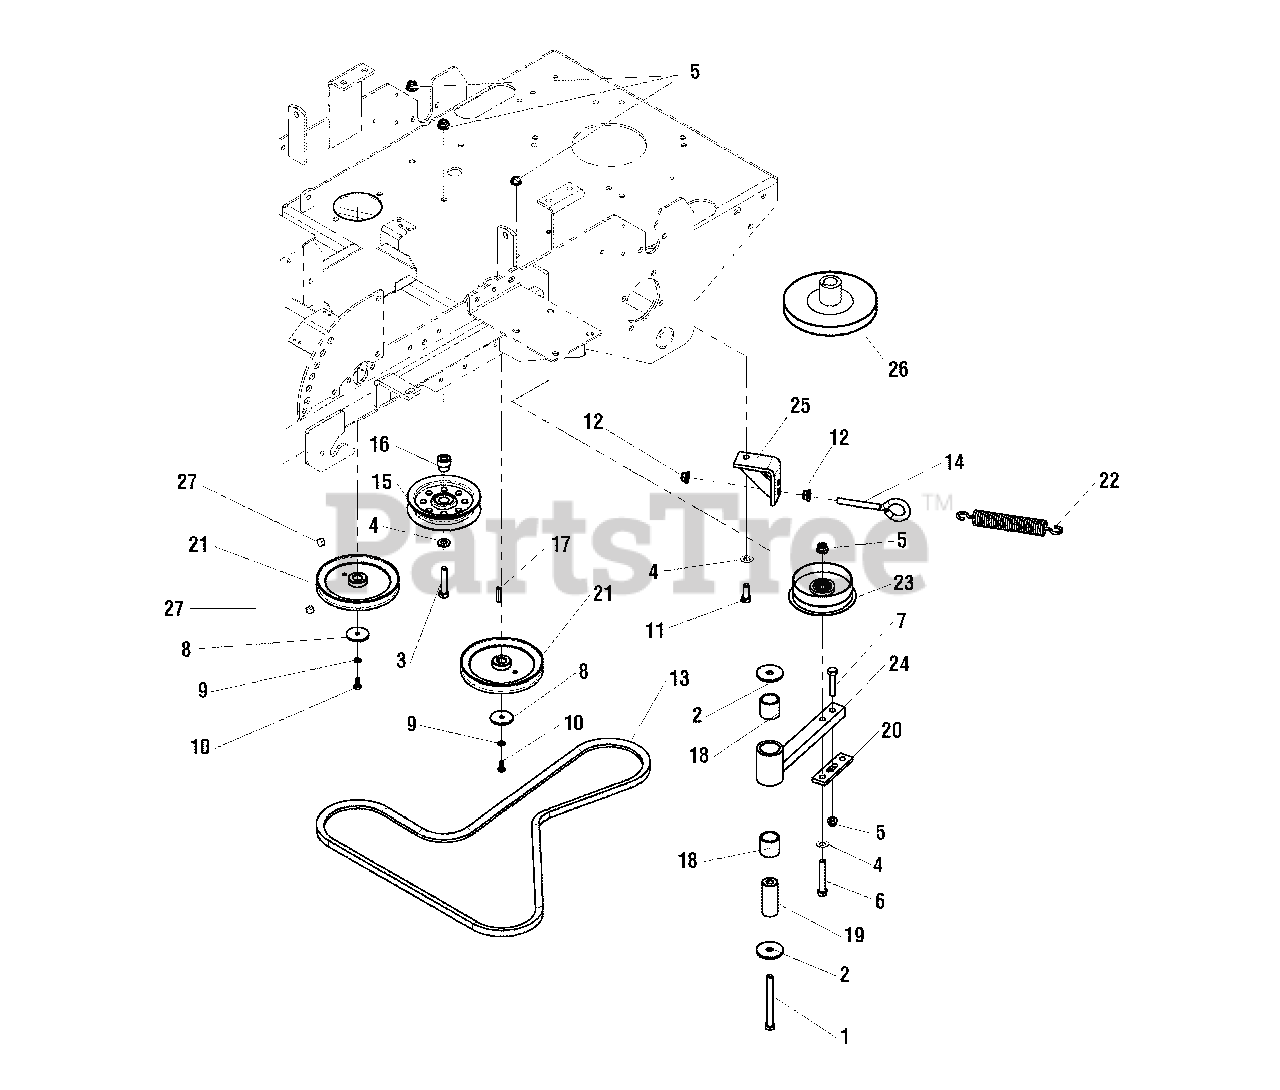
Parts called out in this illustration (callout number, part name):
1	BOLT, 3/8-16 X 4" GD5 CZ
2	WASHER, .41 X 1.75 X .14
3	BOLT, 3/8-16 X 2, GD5, CZ
4	WASHER, 3/8 SAE
5	NUT, 3/8-16 HEX NYLOCK FLANGE
6	BOLT, 3/8-16 X 2-1/2" GD5 CZ
7	BOLT, 3/8-16 X 1-3/4" GD5 CZ
8	WASHER, .265 X 1.50 X .109, YZ
9	WASHER, 1/4" LOCK
10	BOLT, M6-1.0 X 14MM
11	BOLT, 3/8-16 X 1" GD5 CZ
12	NUT, 3/8-16 HEX
13	BELT, DECK DRIVE
14	EYEBOLT, 3/8-16 X 4, 2.13THRD, .75EYE, C
15	PULLEY, IDLER
16	SPACER, HYDRO IDLER PULLEY
17	KEY, 5MM SQ W/ RADIUS
18	BUSHING, BRASS, 1.25 X 1 X 1.25
19	SPACER, .39 X 1.00 X 2.55, SS
20	PLATE, ANCHOR, SPRING
21	PULLEY, PUMP DRIVE
22	SPRING, EXTENSION, 1.00
23	PULLEY, IDLER, SINGLE FLANGE
24	WELD, ARM, PUMP DRIVE IDLER
25	WELD, ANCHOR EYEBOLT
26	PULLEY, Crankshaft
27	SET SCREW, 5/16-24 X 3/8, KNURL, W/PATCH
